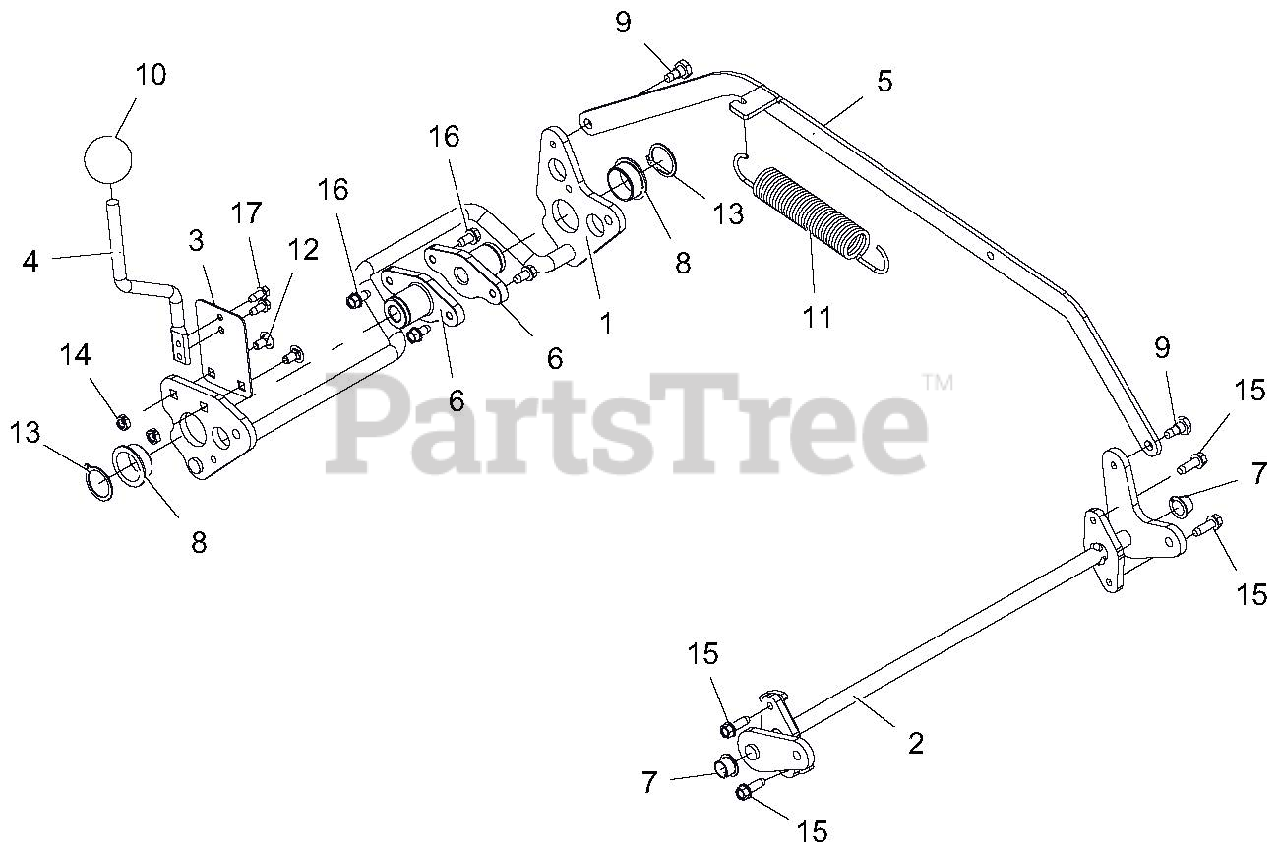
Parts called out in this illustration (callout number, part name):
1	WLDMT, REAR AXLE
2	WMT, LM FRONT AXLE
3	PLATE, HOC SPRING
4	LEVER, HOC ADJUSTMENT
5	LINK, HOC CONNECT
6	HUB, LM REAR AXLE
7	BUSHING, POLYLINER-.50 SPLIT
8	BSHG-FLG 1.0X1.125X.50X1.375 R
9	BOLT, SHLDR .320X.210X.25-20
10	KNOB,BALL -BLACK 1.47" .375-16
11	SG-TENS .121X1.00X6.5 WLD 12
12	@BLT-RDHDSQNK .25-20X.50 G5YZ
13	RG-RTNG-EXT 1.00X.042
14	NUT-LK-CTR JAM .25-20 YWZC
15	SCR-TAP-PM .25-20X.75 TR YWZ
16	SCR-TAP .25-20X.50 HWH TR YWZ
17	@SCR-TAP 12-24X.50 HWH TR YWZC
